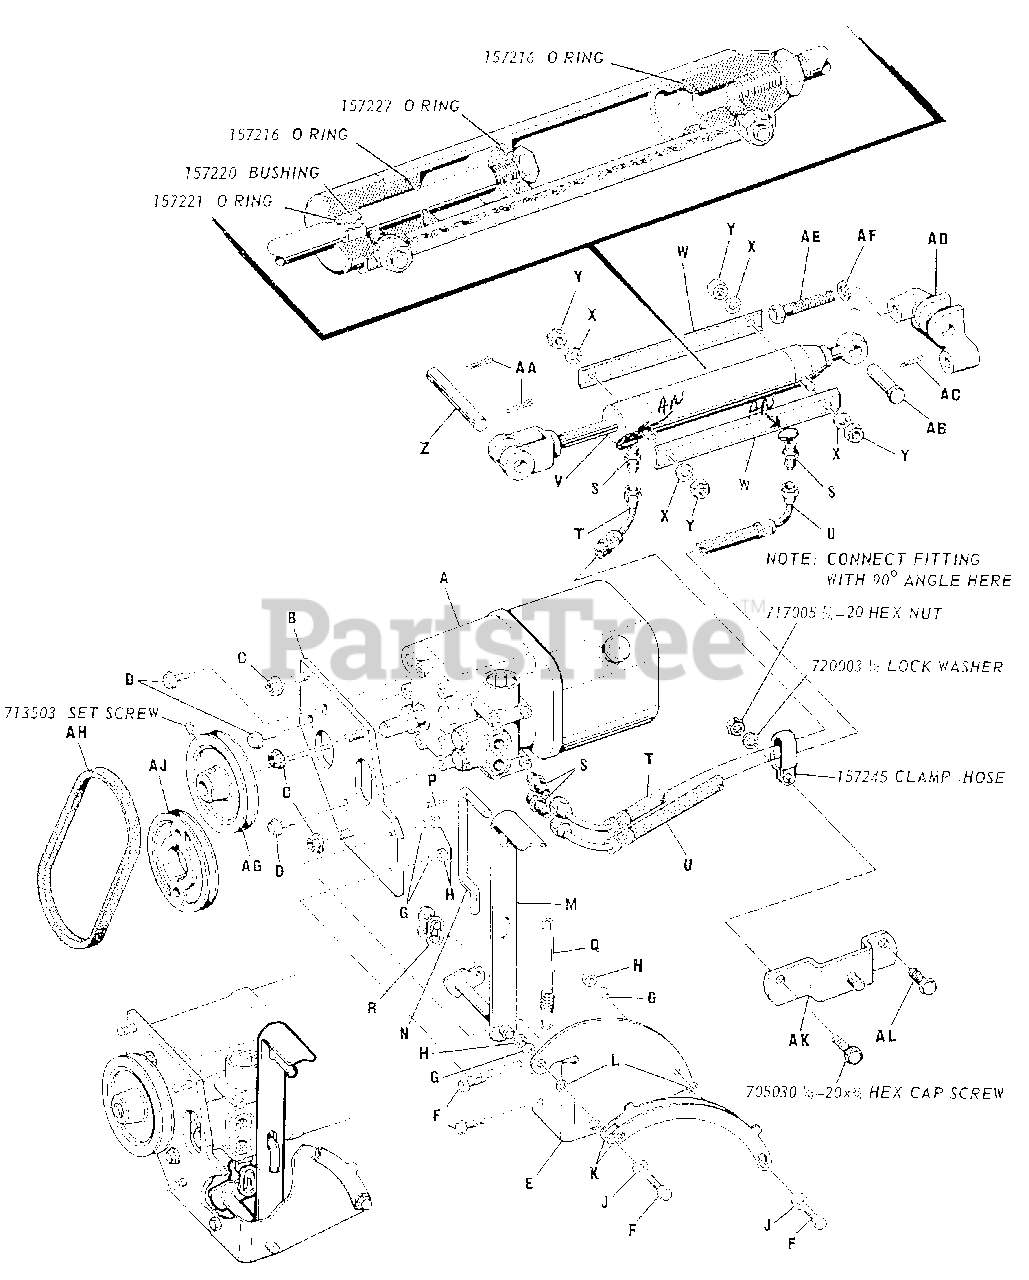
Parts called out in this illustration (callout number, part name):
A	PUMP & TANK
C	NUT, Hex, Whiz Lock, Flange, 5/16-18
D	CAPSCREW, Hex, 1/4-20 x 3/4 Lg.
F	CAPSCREW, Hex, 1/4-20 x 3/4 Lg.
G	WASHER, Lock, 1/4
H	NUT, Hex, Full, 1/4-20
J	WASHER, Flat, 1/4
K	PLATE, Stop
M	LEVER ASSEMBLY
N	ROD, Latch
P	PIN, Cotter, 3/32 x 5/8
R	LINK, Connecting
T	HOSE ASSEMBLY, Short
U	HOSE ASSEMBLY, Long
V	CYLINDER ASSEMBLY
W	BAR, Side
X	WASHER, Lock, 5/16"
Y	NUT, Hex, Full, 5/16-18
AA	PIN, Cotter, 1/8 x 3/4
AB	PIN, Ram Bracket
AC	PIN, Cotter, 1/8 x 3/4
AD	BRACKET, Ram
AE	CAPSCREW, Hex, 7/16-14 x 2-1/4 Lg.
AF	WASHER, Lock, 7/16"
AG	PULLEY, Pump
AJ	PULLEY, Drive
AK	BAR ASSEMBLY
AL	CAPSCREW, Hex, 5/16-18 x 1 Lg.
